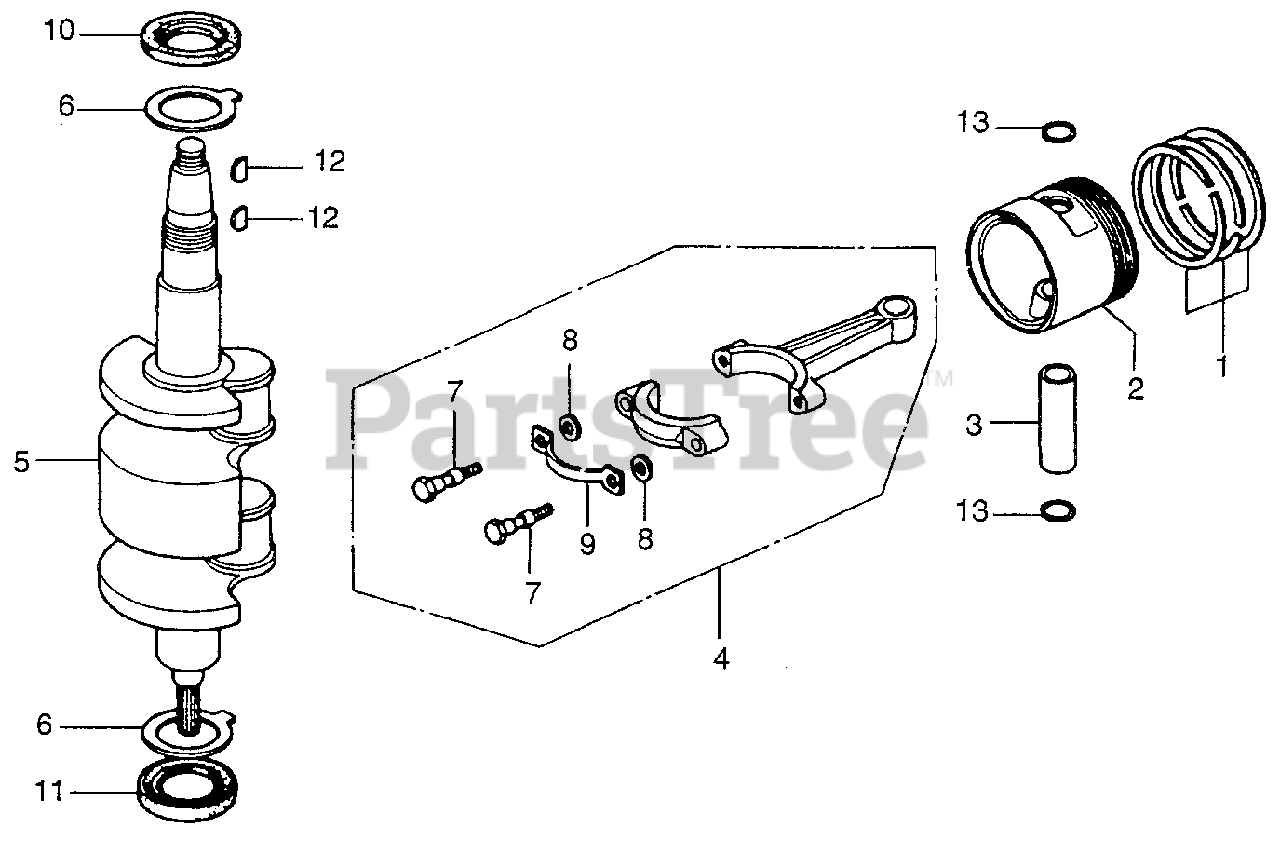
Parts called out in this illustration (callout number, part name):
1	RING SET, PISTON (STD)
1	RING SET, PISTON
2	PISTON (STD)
3	PIN, PISTON (NOT AVAILABLE)
4	ROD SET, CONNECTING
5	CRANKSHAFT
6	BEARING, CRANKSHAFT THRUST (NOT AVAILABLE)
7	BOLT, CONNECTING ROD
8	WASHER (6MM)
9	WASHER, LOCK
10	OIL SEAL A (25X38X7) (NOT AVAILABLE)
11	OIL SEAL B (25X38X7) (NOT AVAILABLE)
12	KEY, WOODRUFF (16X15)
13	CLIP, PISTON PIN (13MM)
